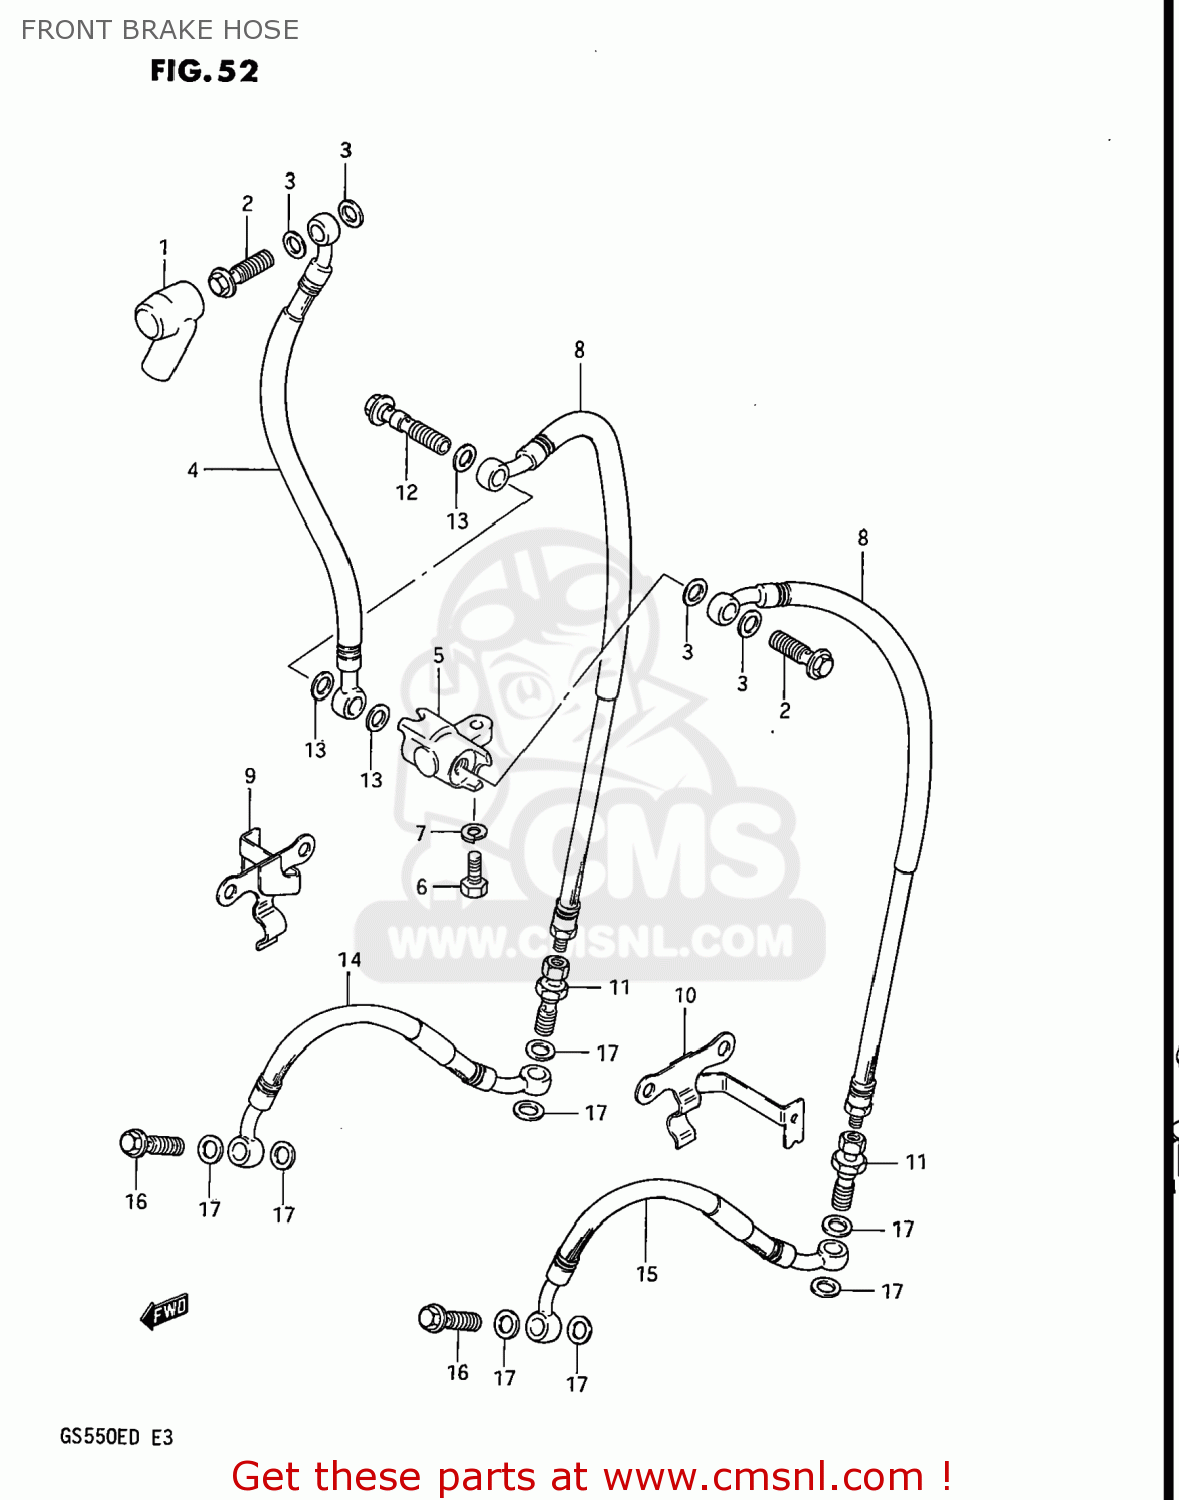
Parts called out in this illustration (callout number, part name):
1	BOOT,MASTER CYLINDER
2	BOLT UNION
3	WASHER
4	HOSE,FRONT BRAKE
5	JOINT,BRAKE HOSE
6	BOLT
7	LOCK WASHER
8	HOSE,BRAKE NO.2
9	CLAMP,FRONT BRAKE HOSE
10	CLAMP,FRONT BRAKE HOSE
11	ADAPTER,BRAKE HOSE
12	BOLT,UNION
13	WASHER
14	HOSE,ANTI-NOSE DIVE,RIGHT
15	HOSE,ANTI-NOSE DIVE,LEFT
16	BOLT UNION
17	WASHER
